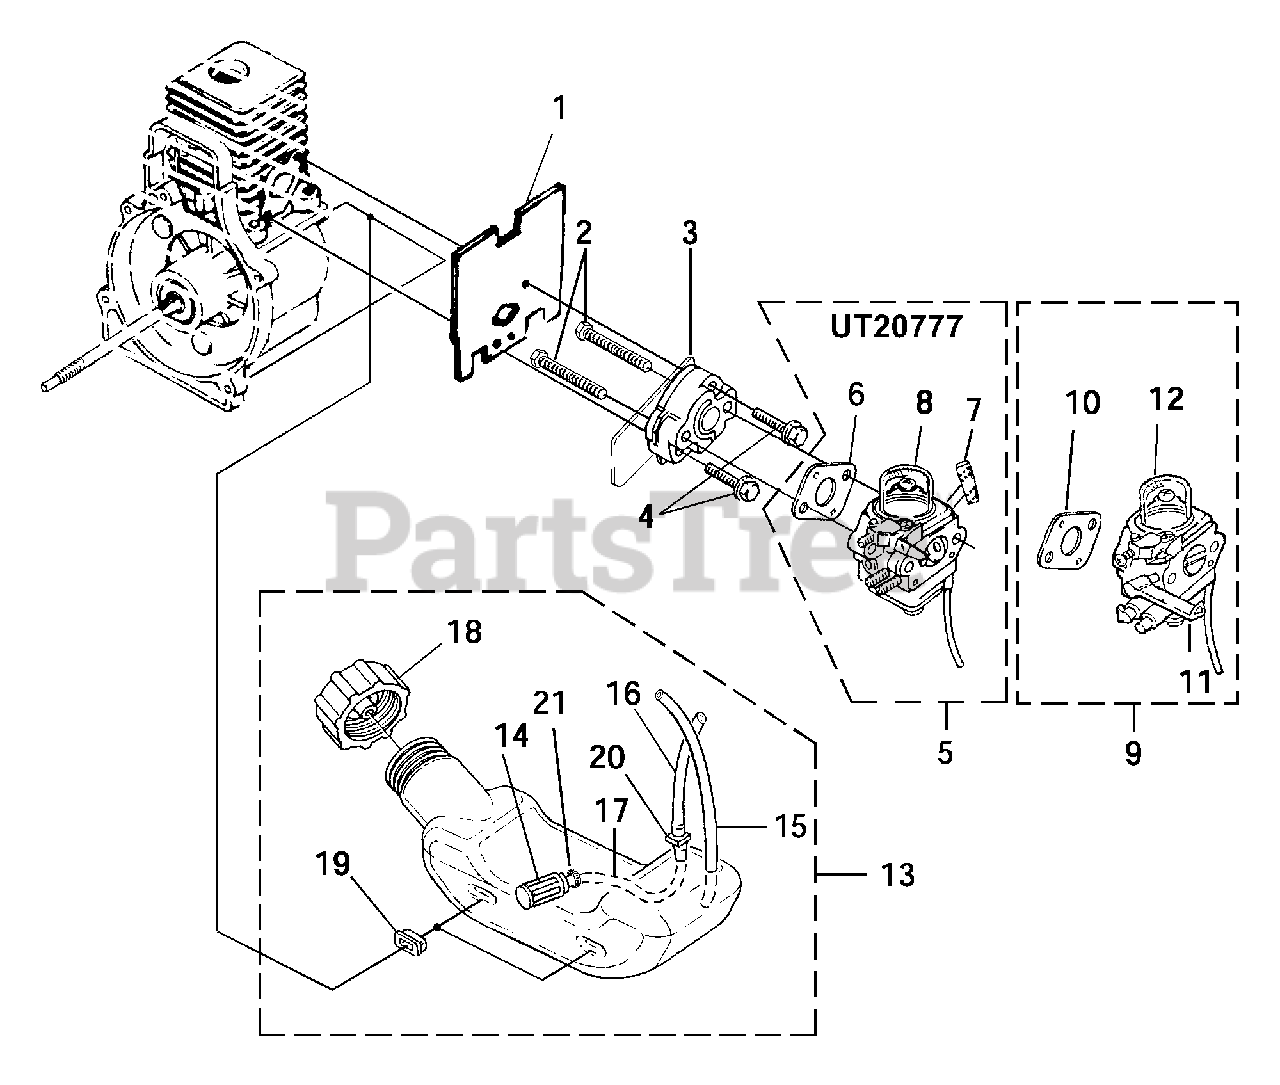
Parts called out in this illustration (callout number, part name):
1	GASKET-Heat Dam
2	SCREW-Machine (10-24 X 2 1/4")
3	HEAT DAM
4	SCREW-Sems (10-24 X 1")
5	CARBURETOR KIT (UT20777)
6	GASKET-Carburetor
7	Lever-Choke (Zama)
8	Bulb-Primer
9	CARBURETOR KIT (Non Clutch)
10	GASKET-Carburetor
11	Lever-Choke
12	Bulb-Primer
13	FUEL TANK ASSY.
14	FILTER-Fuel
15	TUBING-Rubber
16	TUBING-Rubber
17	TUBING-Rubber
18	FUEL CAP
19	BUMPER-Rubber
20	FITTING-Inline
21	CLAMP
